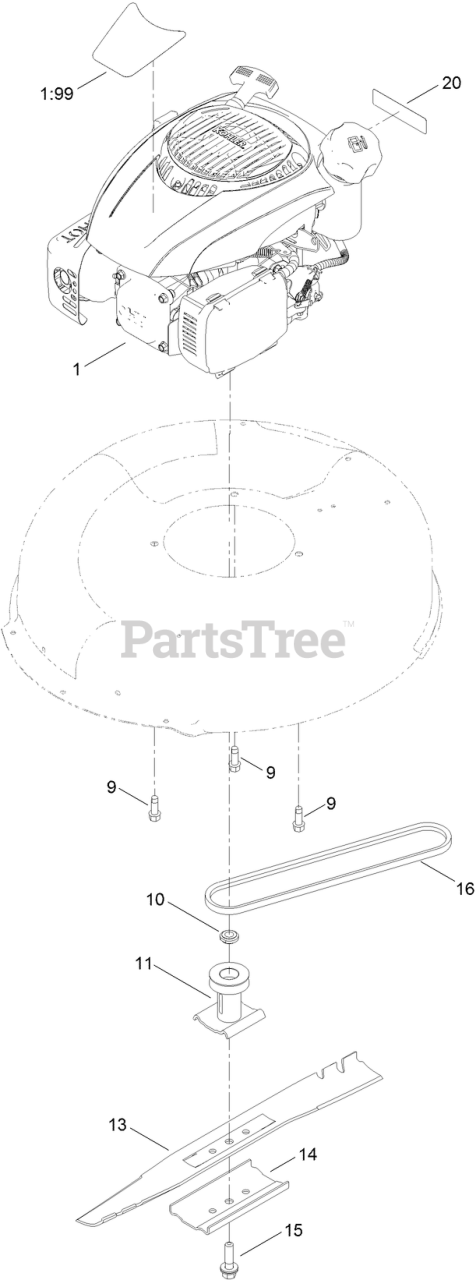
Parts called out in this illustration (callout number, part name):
1:99	DECAL-SHROUD
9	SCREW-TAPTITE
10	SPACER-DRIVER
11	DRIVER-BLADE
14	SUPPORT-BLADE
15	BOLT-BLADE
20	DECAL-ARRESTOR, SPARK
